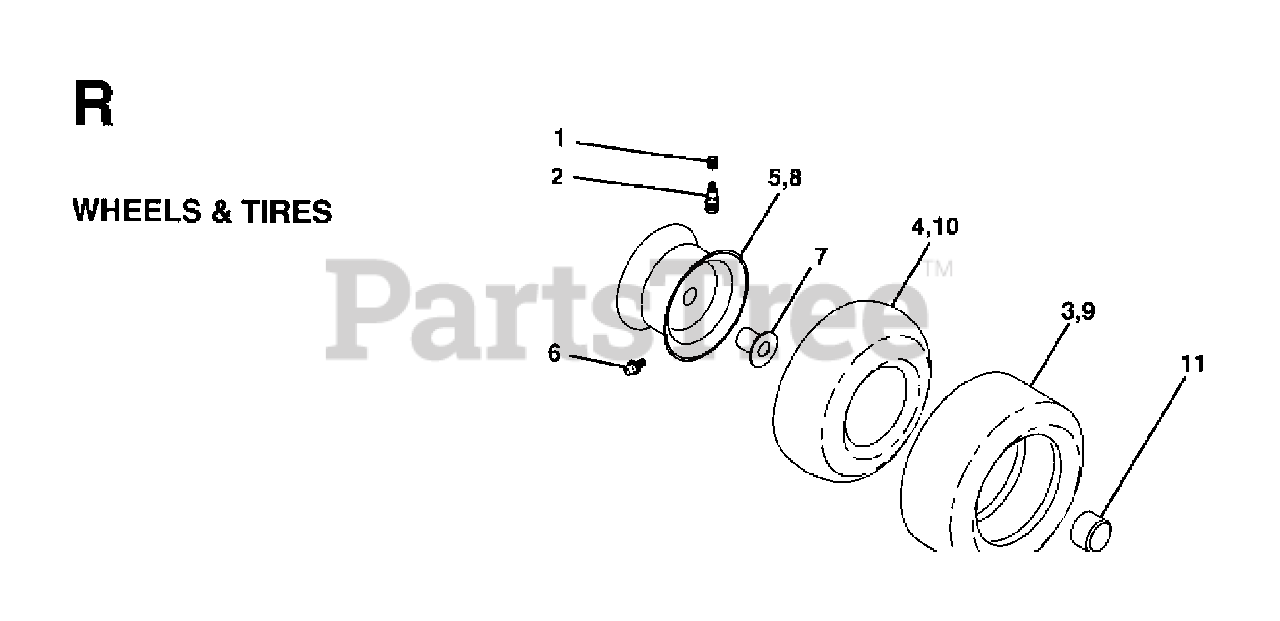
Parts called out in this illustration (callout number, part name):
1	VALVE CAP
2	VALVE STEM LT
3	TIRE HEAVY DUTY
4	TUBE.5.3/4.5/6
5	RIM ASM 6" FRONT SILVER
6	FITTING LT
7	BEARING T
8	RIM ASM 8" REAR SILVER
9	TIRE.TS.20X10-8
10	TUBE
11	CAP-HUB FRONT LT
